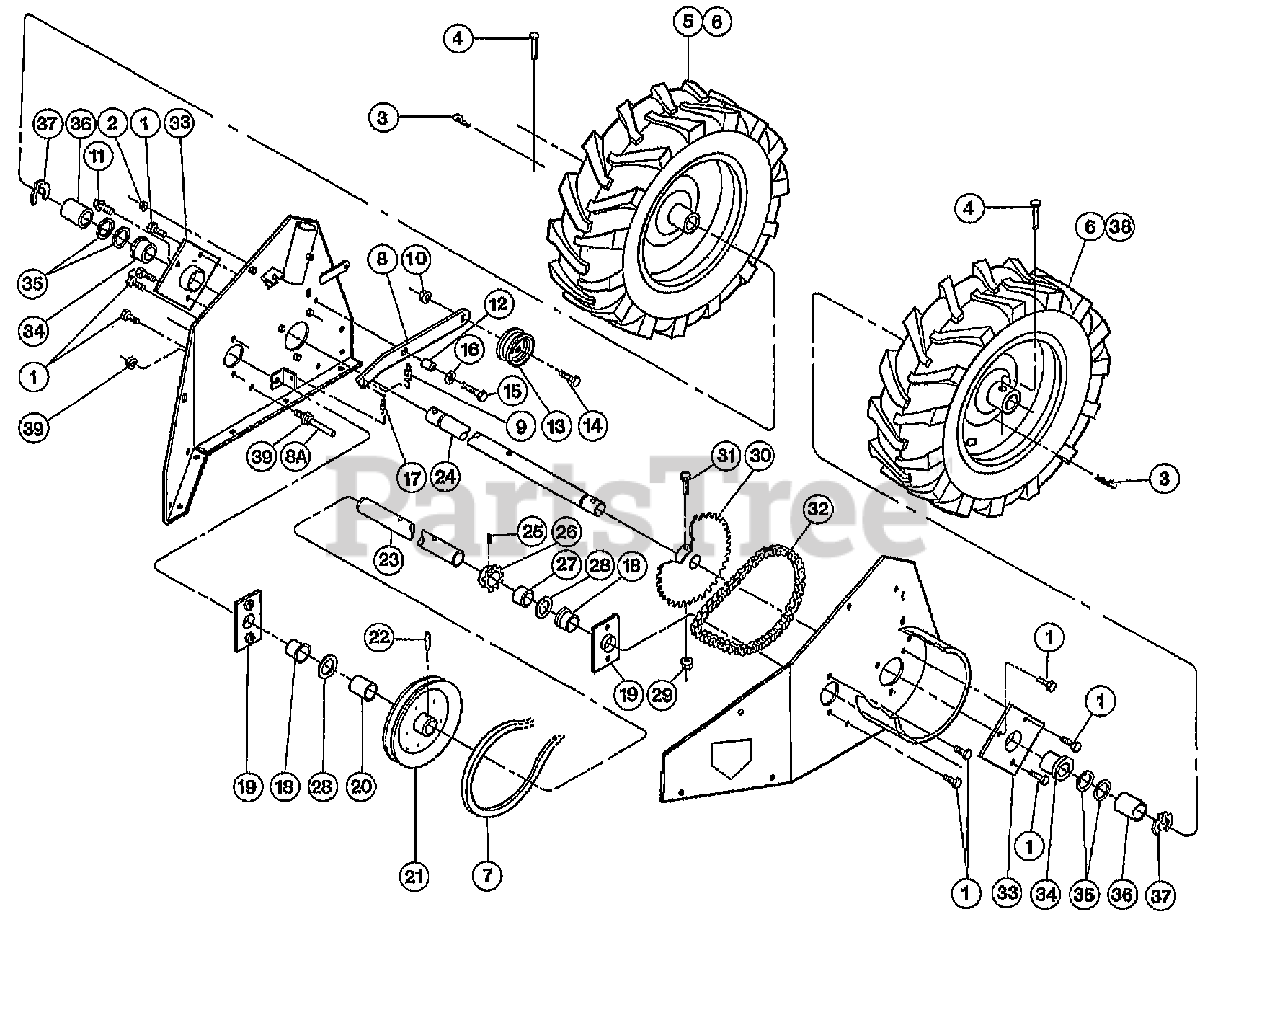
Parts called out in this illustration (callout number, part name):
1	SCR-HFLK 5/16-18X.62 G5
2	NUT-HFLK 5/16-18
3	PIN-CLIP .08
4	PIN-CLEVIS
4	PIN-QUICK RELEASE (REPLACES ITEMS 3 & 4)
5	ASSM-TIRE&WHEEL RH GRAY
6	TIRE-BTT 4.80/4.00X8.00
7	BELT-WHEEL DRIVE
8	ARM-IDLER WHEEL DRIVE
8A	PIN-BELT GUIDE
9	SPRING-CABLE
10	NUT-HFLK 3/8-16
11	SCR-HXFL 5/16-18X.5 G5
12	BUSHING-.5X.31X.843 LG
13	PULLEY-IDLER(BLADE DRIVE)
14	SCR-HFLK 3/8-16X1.50
15	SCR-HH 5/16-18X1.5 G5
16	WASHER-FLAT 5/16 SAE
17	SPRING-RETURN
18	BUSHING-FLANGE JACKSHAFT
19	PLATE-JACKSHAFT PNT.
20	SPACER-JACKSHAFT
21	PULLEY-JACKSHAFT
22	PIN-SPIROL 3/16 X 1.50
23	SHAFT-JACK MACH
24	SHAFT-WHEEL MACH
25	PIN-SPIROL .188X1.12
26	SPROCKET-9T
27	SPACER-JCKSHFT SPKT SIDE
28	WASHER-#1.25X.75X.06
29	NUT-H/LK 5/16-18 NYLOCK
30	SPROCKET-36T WELD
31	BOLT-HH 5/16-18 X 2 G5
32	CHAIN-ROLLER #41
33	FLANGE, AXLE BUSHING
34	BUSHING/AXLY NYLONG
35	SHIM-1.375X1.015X.062
36	SPACER-AXLE T/BLAZER
37	RING-HEAVY EXT .906 ID
38	ASSM-TIRE&WHEEL LH GRAY
39	NUT-TOP/LK 5/16-18 ZP
